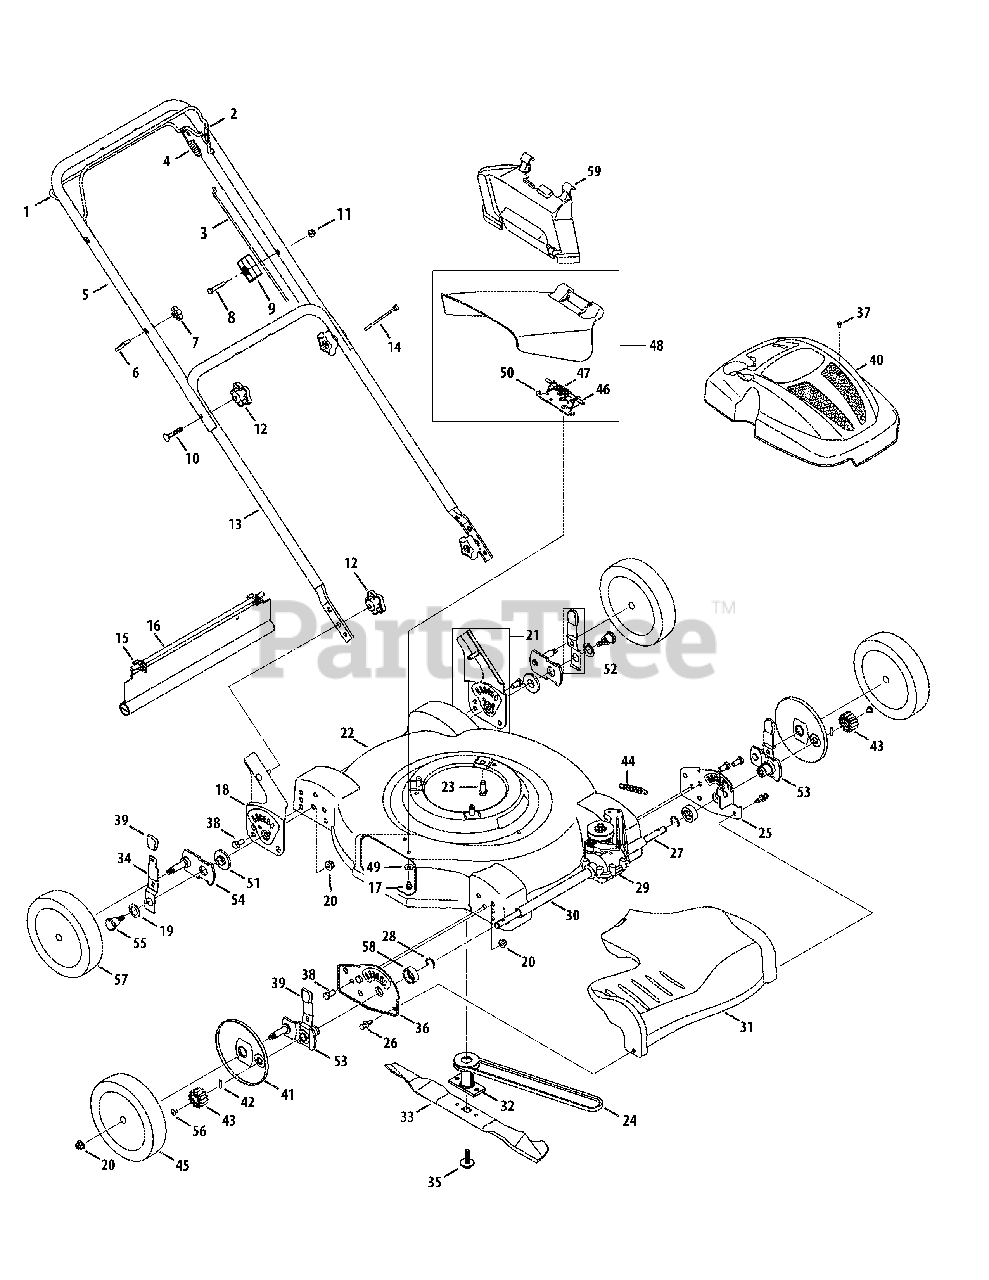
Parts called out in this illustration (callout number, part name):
1	Drive Control
2	Blade Control
3	Blade Control Cable
4	Drive Control Cable
5	Upper Handle
6	Eye Bolt
7	Wing Nut, 1/4-20
8	Hex Screw, 1/4-20 x 1.50
9	Cable Mount
10	Carriage Bolt, 5/16-18 x 2.0
11	Flange Lock Nut, 1/4-20
12	Star Knob
14	Cable Tie
15	Hinge Clip
16	Trail Shield
17	Hex Screw, 1/4-20 x.500
18	Handle Bracket Assy - RH
19	Bell Washer, .760 x 1.25 x.041
20	Lock Nut, 3/8-16
21	Handle Bracket Assembly - LH
22	22" Deck Assembly
23	Hex Washer Scr., 3/8-16 x 1.0
24	V-Belt, 3L x 32.90
25	Forward Height Adj. Plate - LH
26	Rivet
27	Sleeve Spacer, .550 ID x 2.22
28	Retainer Ring
29	Transmission Assy. Comp.
30	Sleeve Spacer, .550 ID x 8.51
31	Transmission Cover
32	Blade Adapter
33	22" Mulching Blade
34	Spring Lever
35	Sems Screw, 3/8-24 x 1.5
36	Forward Hght. Adj. Plate - RH
37	Screw, #12-16 x 1.00
38	Hex Cap Screw, 3/8-16 x.75
39	Adjustment Knob
40	Engine Shroud
41	Wheel Dust Cover
43	Spur Gear 14T - RH
43	Spur Gear 14T - LH
44	Ext. Spring, .47 OD x 2.50
45	Front Wheel, 8 x 1.8
46	Hinge Pin
47	Torsion Spring
48	Side Discharge Assembly
49	Bell Washer, .265 ID x.75 OD
50	Deflector Chute Adapter
51	Height Adjustment Bearing
52	Rear Hgt. Adj. Lever Assembly
53	Front Lever Assembly - LH
53	Front Lever Assembly - RH
54	Rear Pivot Arm Assembly
55	Shoulder Screw, 3/8-16
56	Screw, 1/4-20 x .390
57	Rear Wheel, 8 x 1.8
58	Bearing Support Spacer
